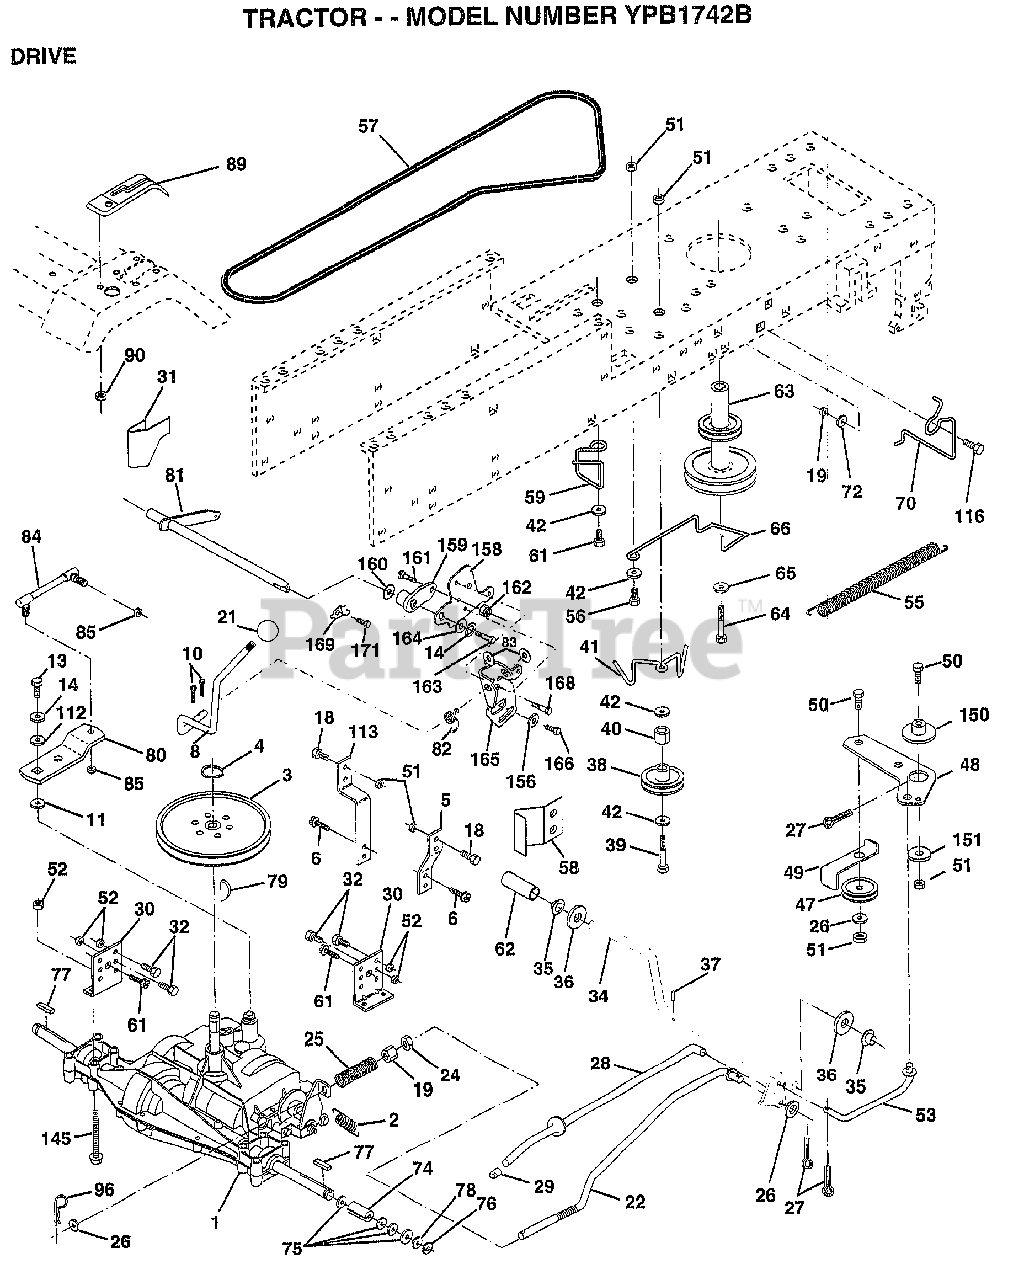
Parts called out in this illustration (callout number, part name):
2	SPRING.BRAKE.RETU
3	PULLEY TRANS
5	STRAP TORQUE
6	SCREW
8	ROD.SHIFT.FENDER.ADJ.LT.CRD
10	PIN COTTER 1/8
11	WASH-SHFT PLT LT
13	BOLT.1/4-28.W/PAT
14	LOCKWASHER
18	BOLT
19	NUT
21	KNOB DLX BLK/BLK
22	BRAKE ROD
24	NUT
25	KNOB DLX BLK/BLK
26	WASHER
27	COTTER PIN
28	ROD.BRAKE.PARK.LT
29	PLUNGER CAP T
30	TRANSAXLE MTG BKT
31	"KEEPER,BELT LH T"
32	BOLT
34	SHAFT ASM-PEDAL F
35	NYLON BEARING
36	WASHER LT
38	FLAT IDLER PULLEY
39	BOLT
40	SPACER T
41	"KEEPER,BELT.IDLER FLAT"
42	WASHER
48	BELLCRANK.CLUTCH
49	RETAIN BELT
53	"LINK, CLUTCH T"
55	"SPRING, RETURN LT"
58	"KEEPER,BELT RH T"
59	KEEPER BELT CNTSP
61	SCREW
62	"COVER,PEDAL"
63	PULLEY.ENGINE
64	BOLT
65	LOCKWASHER
66	KEEPER-BELT
70	KEEPER BELT ENG
72	WASHER
74	SPACER AXLE
75	WASHER
76	E-RING LT
77	SQUARE KEY
78	WASHER
80	"ARM.SHIFT.20""TIRE"
81	SHAFT.ASM.CROSS
82	"SPRING,TORSION"
83	WASHER
84	LINK.TRANSAXLE.PMST/DANA
85	NUT.CNT.LOCK.1/4
89	CONSOLE.SHIFT.SLT
90	NUT
96	RETAINER M
112	WASHER LT
113	"STRAP,TORQUE"
116	BOLT RDHD 3/8-16
145	BOLT.HEX.FLGHD
150	BUSHING.BELLCRANK.GRD.DR
151	WASHER
156	WASHER.SRRTD.5/16
158	BRKT.SHIFT.MOUNT
159	HUB.SHIFT
160	WASHER
161	BOLT T
164	WASHER.5/8X.281X10GA
165	BRKT.PIVOT.LEVER
166	SCREW.5/16-18X5/8
168	BOLT.SHOULDER.5/16-18X.561
169	PLATE.FASTENING
171	SCREW LT
